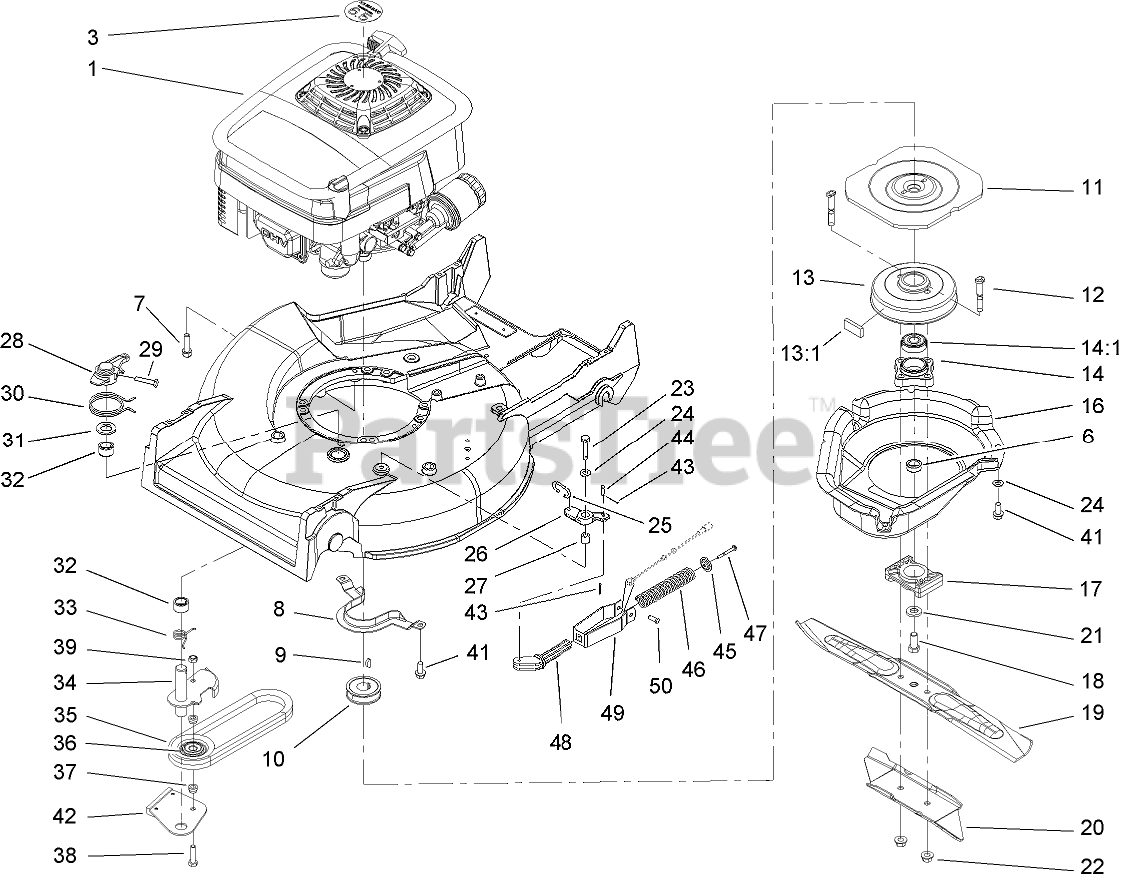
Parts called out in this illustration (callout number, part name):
1	ENGINE-KAWASAKI
3	DECAL-RECOIL
6	SPACER-SHAFT, OUTPUT
7	SCREW-TAPTITE
8	BRACKET-GUIDE, BELT
9	KEY-WOODRUFF
10	PULLEY-DRIVER
11	FLYWHEEL-BBC
12	BOLT-BLADE
13	BRAKE DRUM ASM
13:1	DAMPENER-VIBRATION
14	HUB ASM
14:1	BEARING-BALL
16	SHIELD
17	SPACER-BLADE
18	SCREW-HH
19	Blade
20	STIFFENER-BLADE
21	CAP-ENGINE
22	NUT-LOCK
23	SCREW-HH
24	WASHER-PLAIN
25	LINK-CONTROL
26	BELLCRANK
27	SLEEVE-BELLCRANK
28	LEVER
29	SCREW-HH
30	SPRING-TORSION
31	WASHER
32	BEARING
33	SPRING-TORSION
34	ARM-IDLER
35	V-BELT
36	PULLEY-IDLER
37	SPACER-PULLEY, IDLER
38	SCREW-HH
39	NUT-LOCK, NI
41	SCREW-HWHTF
42	BRAKE PLATE ASM
43	PIN-COTTER
44	PIN-SPRING
45	RETAINER-SPRING
46	SPRING
47	SCREW-HWHTF
48	GUIDE-SPRING
49	BRACKET-SPRING
50	PIN-CABLE
